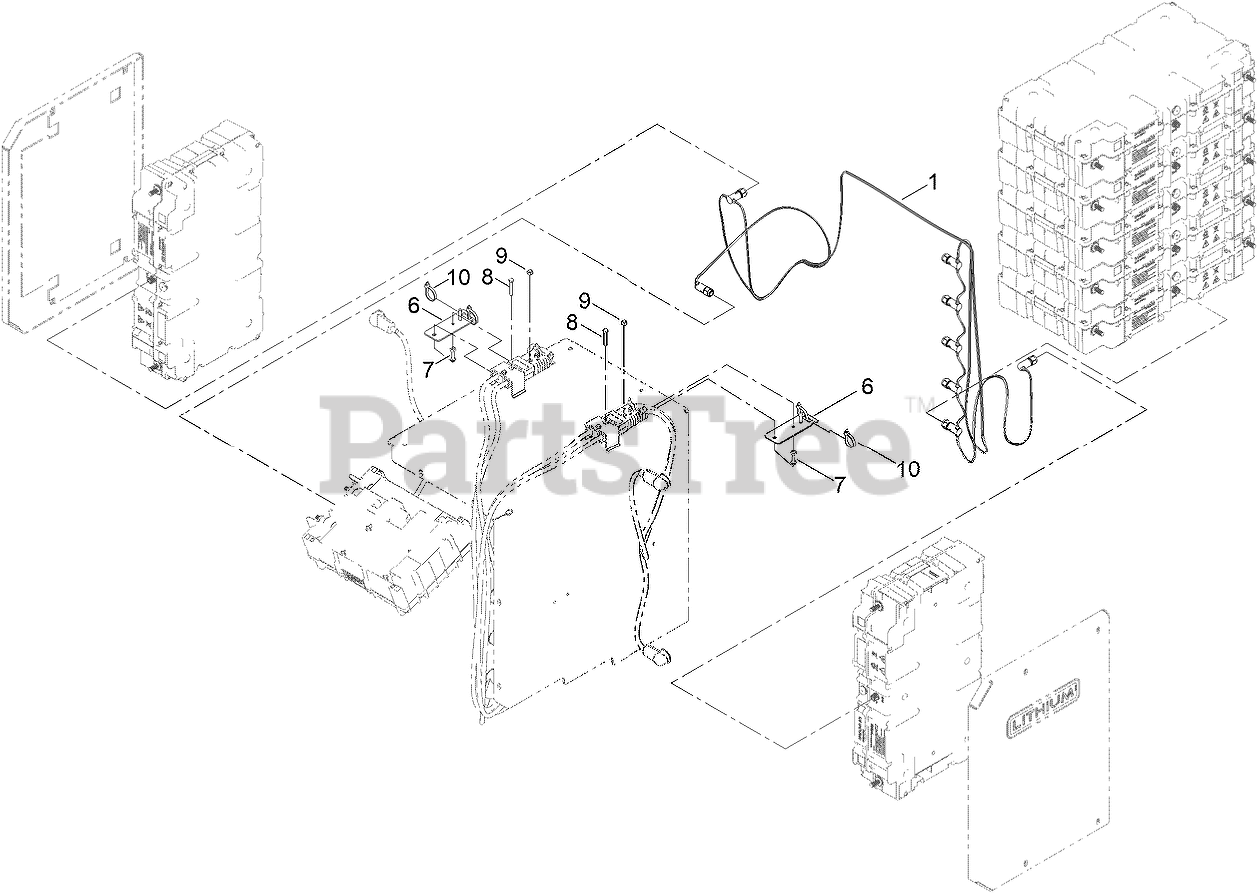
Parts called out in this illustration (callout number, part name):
1	HARNESS-WIRE, SAMSUNG INTERFACE
6	BRACKET-CONNECTOR
7	SCREW-HWH
8	SCREW-HH
9	NUT-LOCK, NI
10	TIE-CABLE
